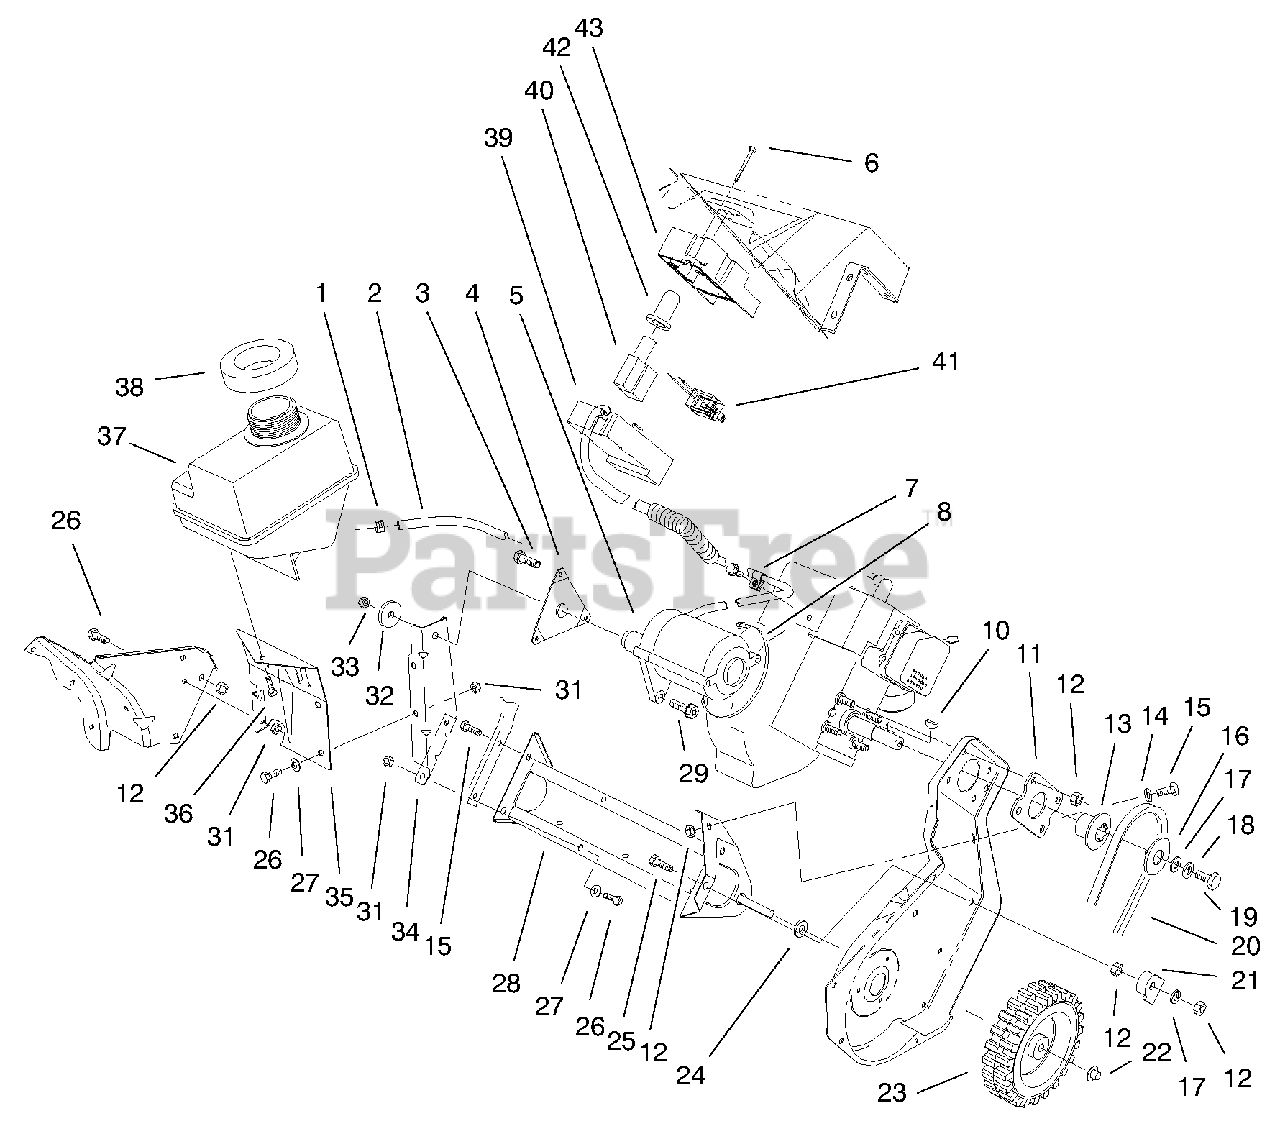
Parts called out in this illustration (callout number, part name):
2	Gas Line
3	Washer-Lock/Ext
4	Bracket/Stud ASM
5	Starter Motor ASM 120 Volt] (only on: 28222)
6	Screw-Plastite (only on: 28222)
7	Clamp R (only on: 28222)
8	Tie-Cable
10	Key-Woodruff
11	Engine Plate
12	Nut-Lock Ni
13	Hub-Half Sheave
14	Washer-Flat
15	Screw-HH
16	Cap-Half Sheave
17	Washer-Flat
18	Washer-Belleville
19	Screw-Hex Hd Cs
20	Drive V-Belt
21	Guide-Cable
22	Retainer-Push On
24	Wheel Spacer
25	Screw-HH
26	Screw-HH
27	Washer-Flat
29	Screw-Mtg Torx (only on: 28222)
31	Nut-Lock Ni
32	Engine Support Washer
33	Nut-Lock Ni
34	Engine Support
35	Tank Bracket
36	Screw-Self TAP
37	Fuel Tank
38	Foam Seal
39	Base Housing Switch (only on: 28222)
40	Switch,Starter (only on: 28222)
41	Power Plug (only on: 28222)
42	Boot,Switch (only on: 28222)
43	Cap Housing Switch (only on: 28222)
